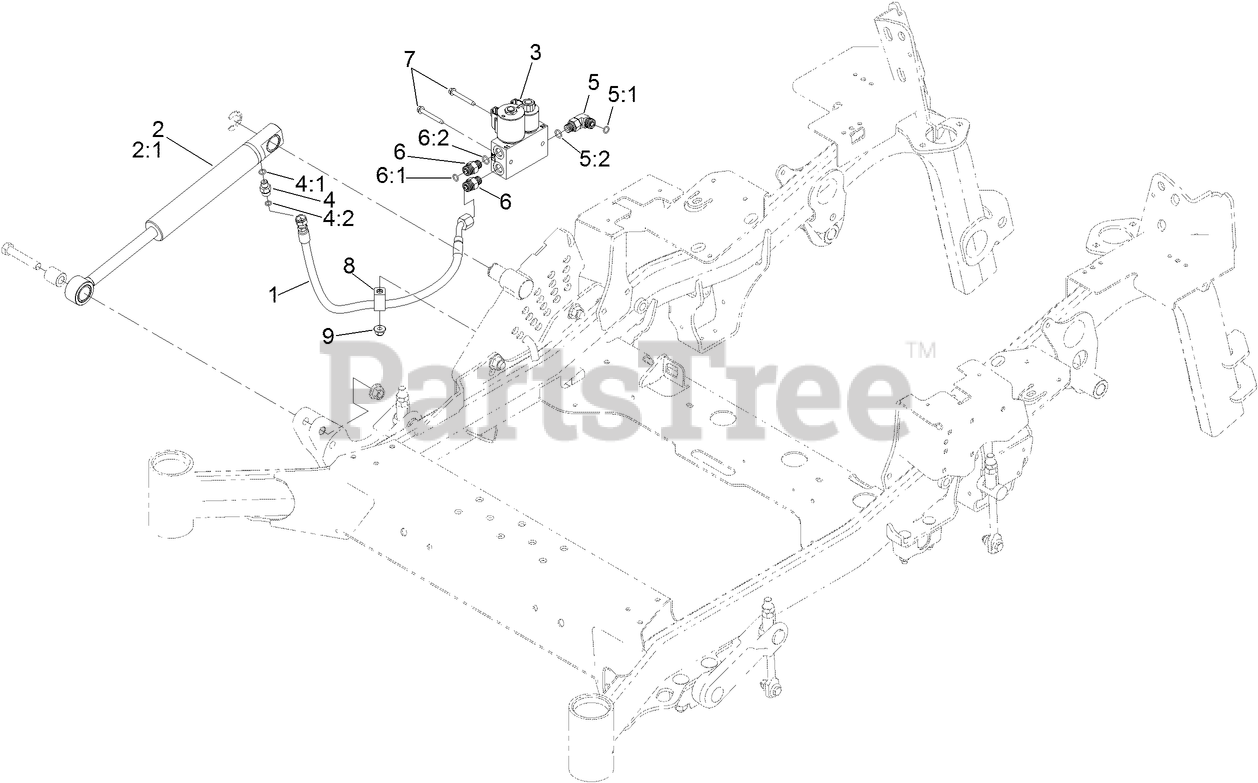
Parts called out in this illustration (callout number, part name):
1	HOSE ASM
2:1	KIT, CYL REPAIR
3	DECK LIFT VALVE ASM
4	FITTING-HYD, STRAIGHT
4:1	O-RING
4:2	O-RING
5	FITTING-ELBOW, 90 DEG
5:1	O-RING
5:2	O-RING
6	FITTING-STRAIGHT
6:1	O-RING
6:2	O-RING
7	SCREW-HWHTF
8	CLIP-LOOM
9	NUT-HF, NI
